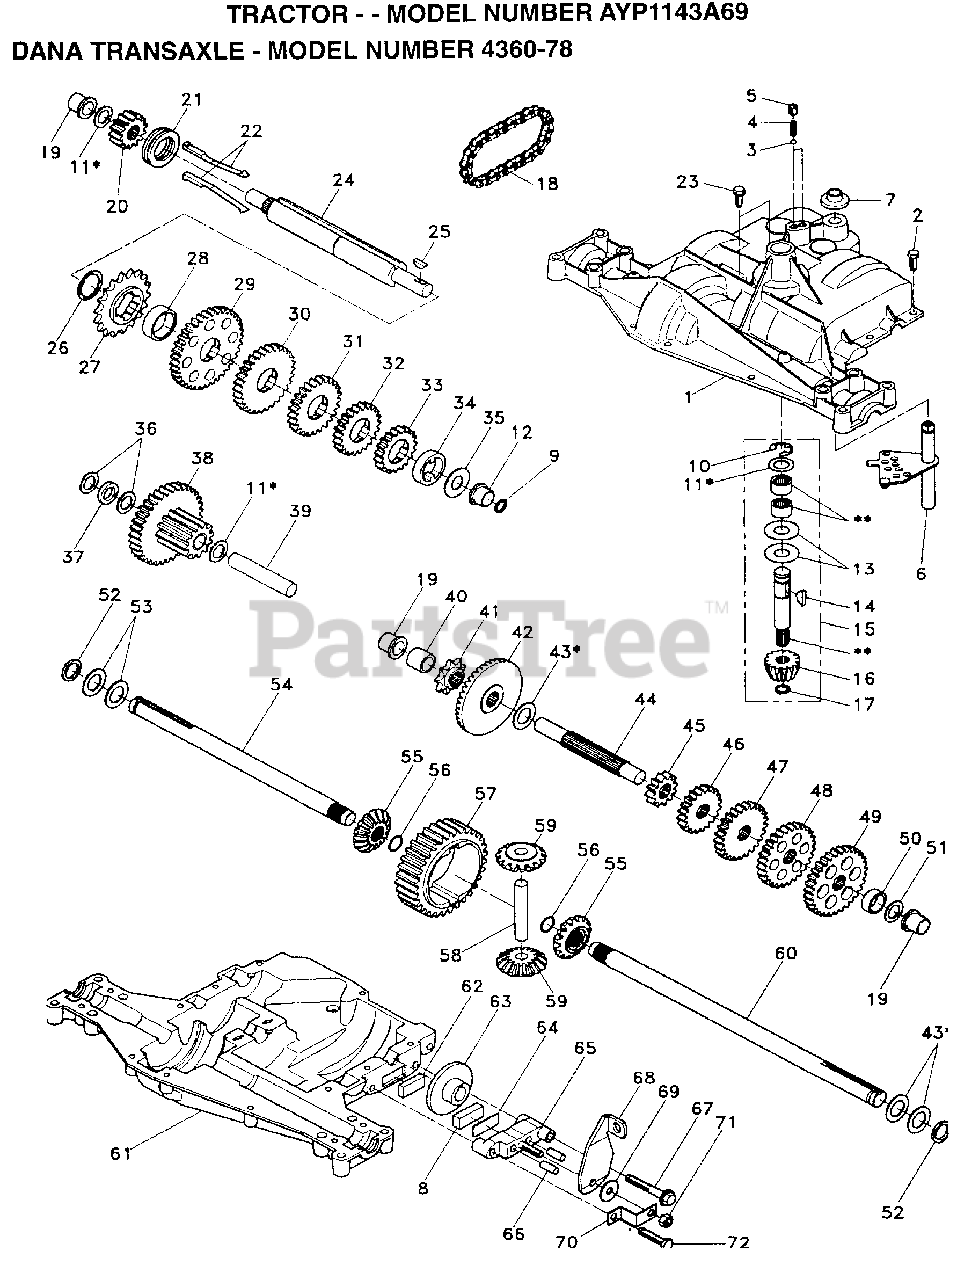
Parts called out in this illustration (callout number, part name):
1	HOUSING UPPER TRN
4	"SPRING, DETENT LT"
5	"SCREW, SET LT"
6	KIT SHIFTER ASM
7	SHIFTER BOOT
8	PUCK T
9	SEAL OIL DANA5416
11	ASM KIT SHIM 4689
13	WASHER T
14	KEY WOODRUFF-DANA
15	AS KIT INPUT SHFT
16	PINION 14T T
17	"RING,RETAINING LT"
18	"CHAIN,24 PTCH LT"
19	BEARING.FLNG.5510
20	GEAR SPUR 14 TTH
21	COLLAR CLUTCH
22	ASM KIT CLTCH KEY
23	SCREW TAP W/SEAL
24	SHAFT INTERM DANA
25	WOODRUFF KEY
26	"RING,RETAINING LT"
27	SPROCKET 18T T
28	SPACER YT
29	GEAR SPUR 37 TTH
31	GEAR 25T LT
32	GEAR SPUR 22 TT
33	SPUR GEAR 19T
34	SPACER
35	"WASHER, PLAIN LT"
36	WASHER 025
37	SPACER
38	ASSM GEAR COMB
39	SHAFT IDLER
39	WASHER LT
40	SPACER T
41	SPROCKET 9T LT
43	ASM KIT SHIM
44	SHAFT T
45	GEAR SPUR 12 TTH
47	"GEAR, SPUR 25T LT"
48	GEAR 28T T
49	"GEAR, SPUR 31T LT"
51	WASHER 060
52	NEOPRENE WASHER
53	WASHER 031
55	GEAR 15T T
56	"RING,RETAINING LT"
58	SHAFT T
59	GEAR 1ST T
61	HOUSING LOWER TNS
62	PUCK T
63	BRAKE DISC. T
64	SPACER LT
66	PIN T
71	NUT.LOCK.5/16-24
72	"SCREW, TAPPING LT"
